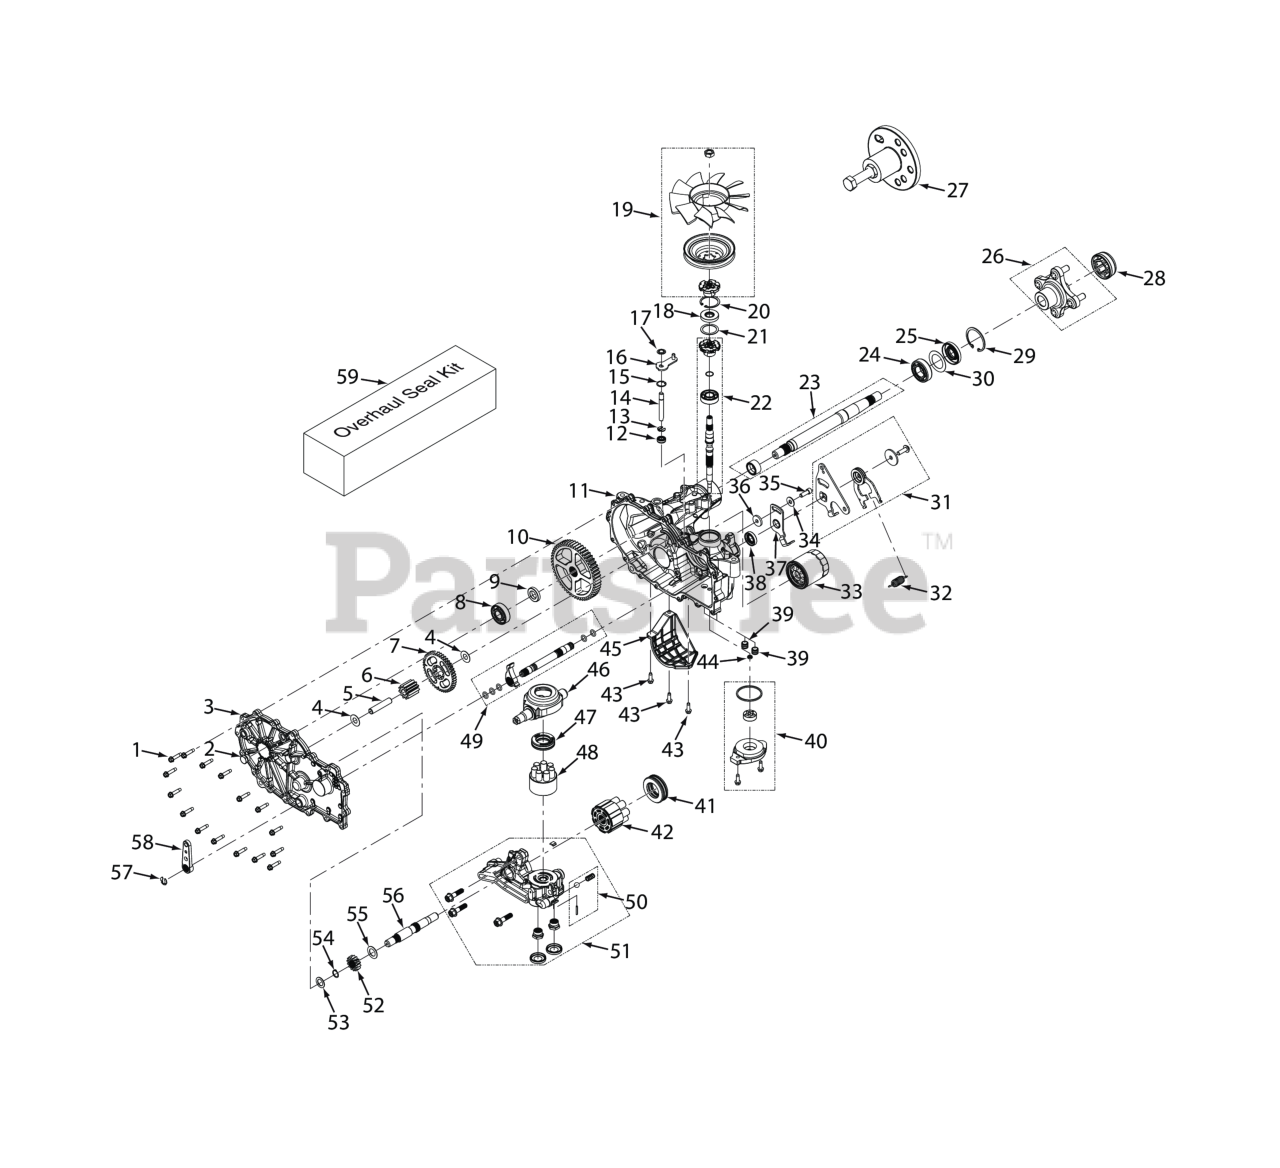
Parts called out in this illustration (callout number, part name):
1	Bolt, Hex Head 1/4-20 x 1-1/8"
2	Plug, External Hex Vent 9/16-18
3	Kit, Side Cover LH
3	Kit, Side Cover RH
4	Washer, .5 x 1.0 x .03
5	Jackshaft Pin
6	Gear, 11T
7	Gear, 45T
8	Kit, Bearing
9	Spacer, .750 x 1.320 x .257
10	Gear, 54T
11	Kit, Housing LH
11	Kit, Housing RH
12	Seal, Lip, .375 x .75 x .25
13	Ring, .Retaining .375 External
14	Rod, By-Pass
15	R i n g , Retaining .750 Internal
16	Arm, Bypass (LH)
16	Arm, Bypass (RH)
17	Ring, Retainging .375 External
18	Seal, Lip 17 x 40 x 7
19	Kit, Fan/Pulley
20	R i n g , Retaining 2.06 Internal
21	Washer, 1.23 x 1.56 x .04
22	Kit, Input Shaft
23	Kit, Shaft, Axle
24	Bearing, Ball 1.0 x 52 x 15 Open
25	Seal, Lip TC4 1.0 x 2.06 x .38
26	Hub, 4-Bolt
27	Kit, Hub Puller
28	Cap, Axle
29	R i n g , Retaining 2.06 Internal
30	Spacer, 1.355 x 2.035 x .021
31	Kit, RTN Bi-Directional (Right Side)
31	Kit, RTN Bi-Directional (Left Side)
32	Spring, Extension, RTN - 44lbs
33	Filter, Oil
34	Washer, 7/16 x 7/8 OD x .06 HT
35	Bolt, Hex Head Cap Screw 5/16-24 x 1" Patch
36	Spacer, .32 ID x 1.005 OD x .1495 Thk
37	Arm, Neutral (Left Side)
37	Arm, Neutral (Right Side)
38	Seal, Lip 18 x 32 x 7
39	Tube, Charge Triple O-ring
40	Kit, Charge Pump
41	Thrust Ball Bearing Assembly
42	Kit, 16cc Cylinder Block Assembly (steam
43	Bolt, 1/4-20 x 3/4"
44	Kit, Gerotor Seal
45	Filter Guard
46	Trunnion, Swashplate
47	Ball Thrust Bearing
48	Kit, Cylinder Block
49	Kit, Inboard, RH Rot B / LH Rot A (LH)
49	Kit, Inboard, RH Rot A / LH Rot B (RH)
50	Kit, Charge Relief
51	Kit, Charge Relief
51	Kit, Center Section, LH Charge
52	Washer, Flat, .71 x 1.16 x .04
53	Washer, HT .62 ID x 1.0 OD x .05 Thick
54	Ring, Retaining .625
55	Washer, .72 x 1.16 x .04
56	Shaft, Motor
57	Ring, Retaining External .375"
58	Handle, Brake
59	Kit, Outboard, RH Rot A / LH Rot B (RH)
60	Tube, Sealant
